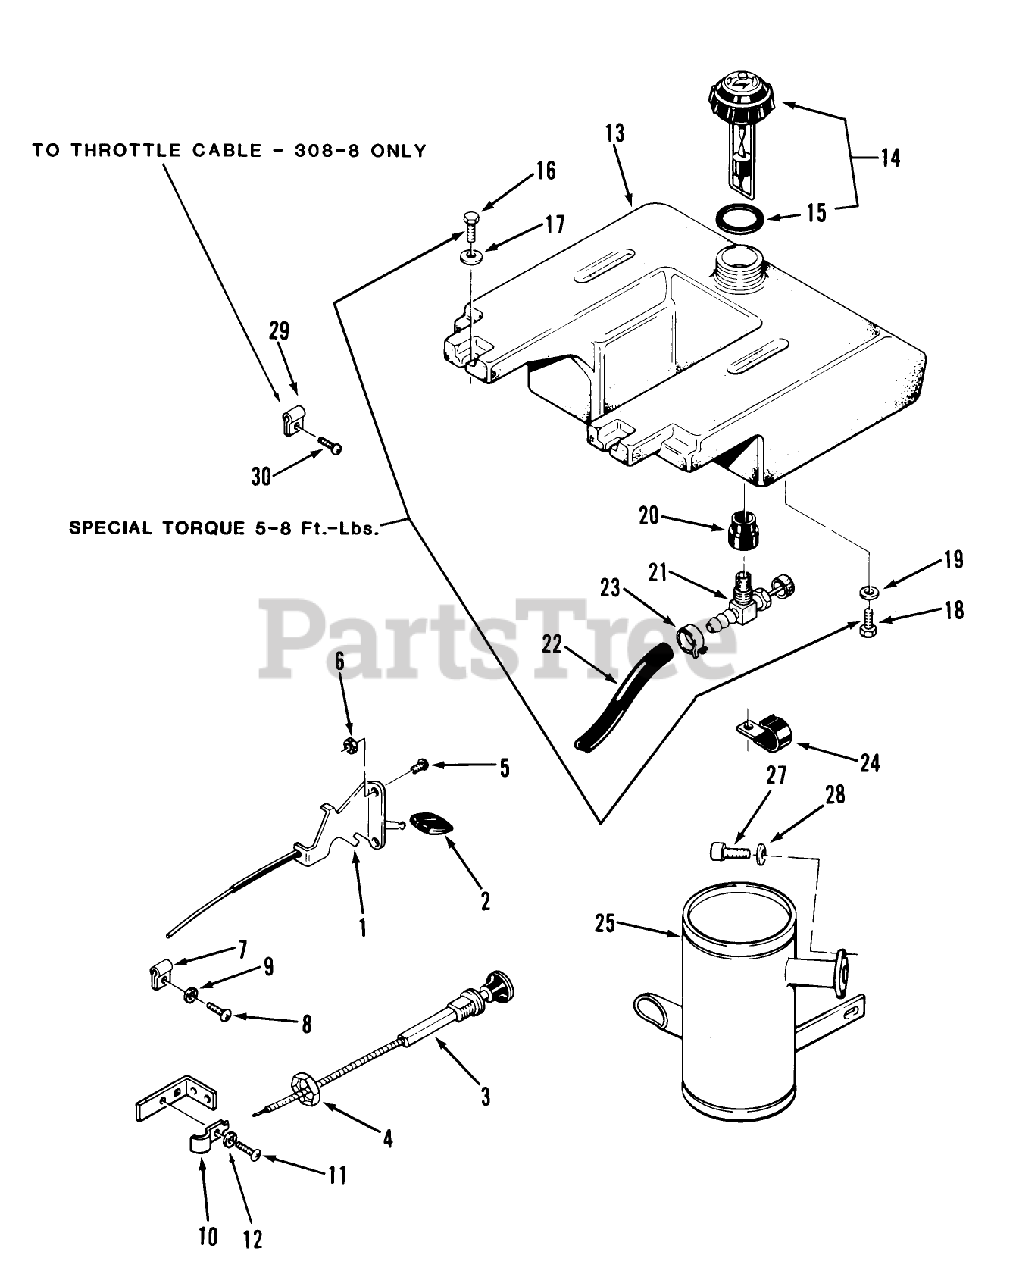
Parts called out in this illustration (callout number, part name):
2	KNOB-THROTTLE
3	CONTROL CHOKE
4	NUT-HEX PALNUT
5	SCREW-PPH
7	THROTTLE CONTROL CLP
10	CLAMP-CABLE
11	Screw PHCR #10-24 x 1/2
13	TANK-FUEL
14	ASSY-GAUGE CAP
21	VALVE-FUEL
27	SHCS 5/16-18X.750
29	CLIP-CABLE
